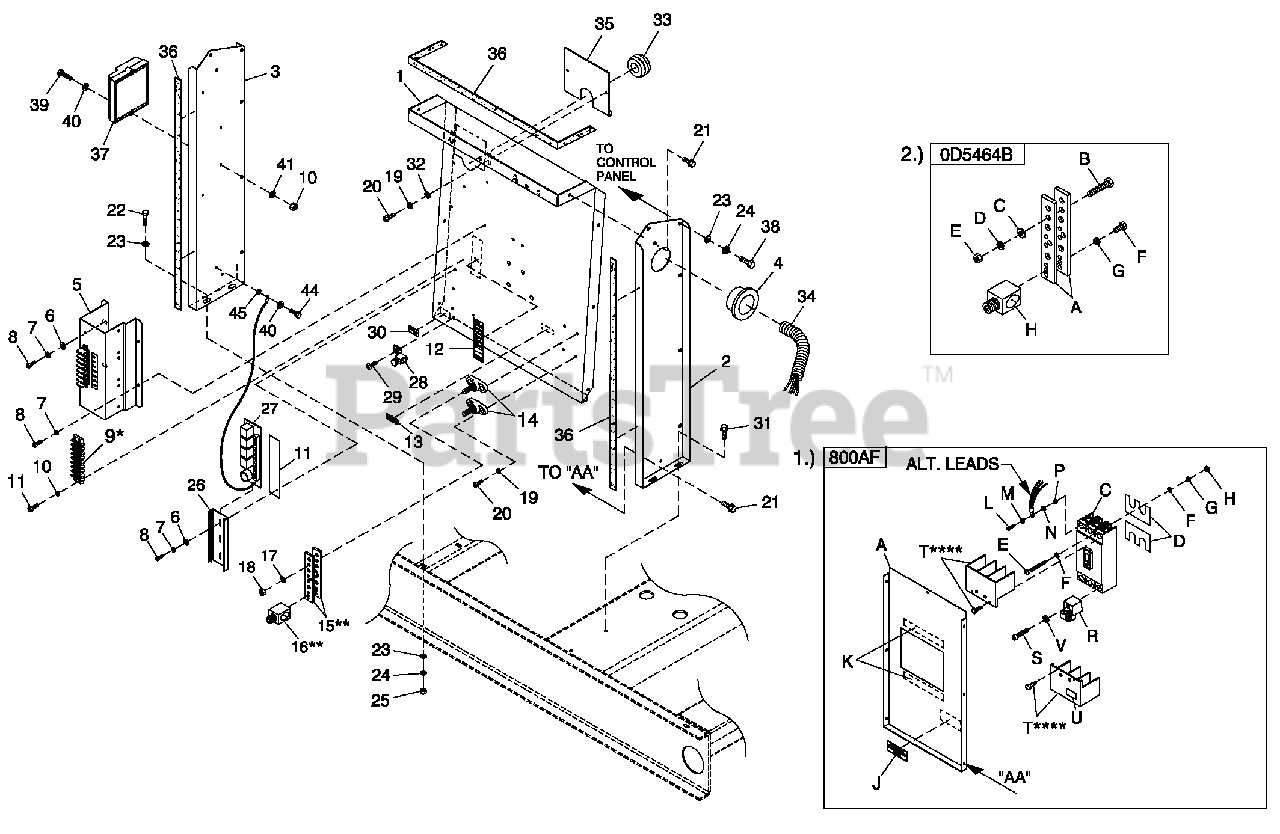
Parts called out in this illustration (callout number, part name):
1	PANEL CB CONN BOX
2	STAND RH CONTROL CPL C5
3	STAND LH CONTROL CPL C5
4	BUSHING SNAP SB-2.5-31
5	INTERFACE 1PH 240V
6	WASHER FLAT M4
7	WASHER LOCK #8-M4
8	SCREW PHTT M4-0.7X 10 ZYC
9	BLOCK TERM 20A 8 X 6 X 1100V
10	NUT HEX #10-32 STEEL
11	DECAL H-100 RB3 CUST CONN
12	DECAL CPL CUST CONN H CTRL
13	DECAL NEUTRAL
14	JUNCTION BLOCK 3/8-16
15	BUS BAR NEUTRAL BLOCK 390
16	LUG SLDLSS 600/250-1/0 X 1/4-28
17	WASHER LOCK 3/8
18	NUT HEX 3/8-16 STEEL
19	WASHER LOCK M5
20	SCREW PHTT M5-0.8X 16 ZYC
21	SCREW THF M6-1 X 16 N WAZ/JS
22	SCREW HHC M6-1.0X20G8.8
23	WASHER FLAT 1/4-M6 ZINC
24	WASHER LOCK M6-1/4
25	NUT HEX M 6X 1 .0G 8Y E LC H R
26	RAIL SNAPTRACK PCB HOLDER BULK
27	ASSY RELAY PCB 12VDC
28	LUG SLDLSS #6-14 X 13/64 CU
29	SCREW HHTT #10-32X3/8 CZ
30	DECAL GROUND LUG
31	SCREW HHTT M6-1.0X 16ZYC
32	WASHER FLAT M5
33	GROMMET 1.25 X .25 X .75
34	CONDUIT FLEX 2.0" ID
35	PLATE WIRE SNGLGALV
36	IAPE ELEC 1/2 FOAM (AS REU'D)
37	ASSY PCB HSB CTRL IGN MODULE
38	SCREW HHC M6-1.0X 16 G8.8
39	SCREW PPHM #10 /32X2
40	WASHER FLAT #10 ZINC
41	WASHER LOCK #10
42	SCREW HHT TM4-0.7X8ZP
43	WASHER SHAKEPROOF EXT #10 STL
A	COVER, CB 803 C5
C	CIRCUIT BREAKERS 800A FRAME
D	INSUL CB 800AF
E	SCREW RHM 1/4-20X1-1/2
F	WASHER FLAT 1/4-M6 ZINC
G	WASHER LOCK M6-1/4
H	NUT HEX 1/4-20 STEEL
J	DECAL CUSTOMER CONNECT INSIDE
K	TAPE ELEC 1/2 FOAM
L	SCREW SHC M10-1.50 X 40 G12.9
M	WASHER FLAT 3/8-M10 ZINC
N	WASHER LOCK 3/8
P	NUT HEX M10-1.5 G8 YEL CHR
R	LUG SLDLSS 3/0-400X3 MCM AL/CU
S	SCREW SHC M6-1.0X50G8.8
T	TERM. COVER VITZROTECH 400AF CB
U	DECAL TERMINAL SHOCK HZD BI
V	WASHER LOCK M6-1/4
A	BUS BAR NEUTRAL BLOCK 390
B	SCREW HHC M8-1.25 X 45 G8.8 FT
C	WASHER FLAT 5/16-M8 ZINC
D	WASHER LOCK M8-5/16
E	NUT HEX M8-1.25 G8 YEL CHR
F	SCREW HHC 1/4-28 X 3/4 G5
G	WASHER LOCK 1/4-M6SS
H	LUG SLDLSS 600/250-1/0 X 1/4-28
